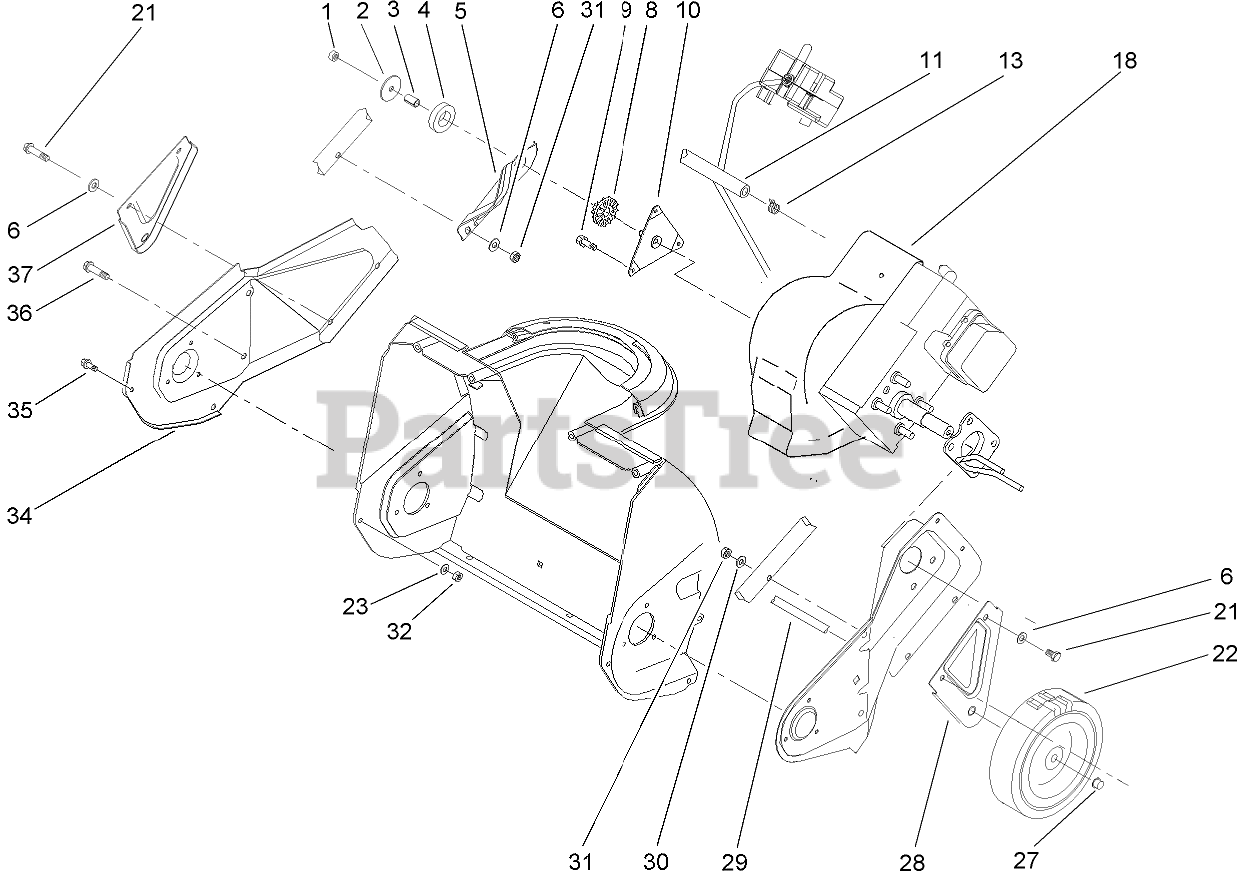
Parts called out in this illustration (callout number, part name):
1	NUT-LOCK, NI
2	WASHER-FLAT
3	SPACER-TUBULAR
4	RING-ISOLATOR
5	BRACKET-SUPPORT, ENGINE
6	WASHER-FLAT
8	BUSHING-ISOLATOR
9	SCREW
10	BRACKET AND STUD ASM
11	LINE-GAS
13	CLAMP-HOSE
21	SCREW-HH
22	WHEEL
23	WASHER-FLAT
27	RETAINER-PUSH ON
28	BRACKET-WHEEL, LH
30	WASHER
31	NUT-LOCK, NI
32	NUT-LOCK, NI
34	PLATE-SIDE, RH
36	SCREW-PLASTIC
37	BRACKET-WHEEL, RH
